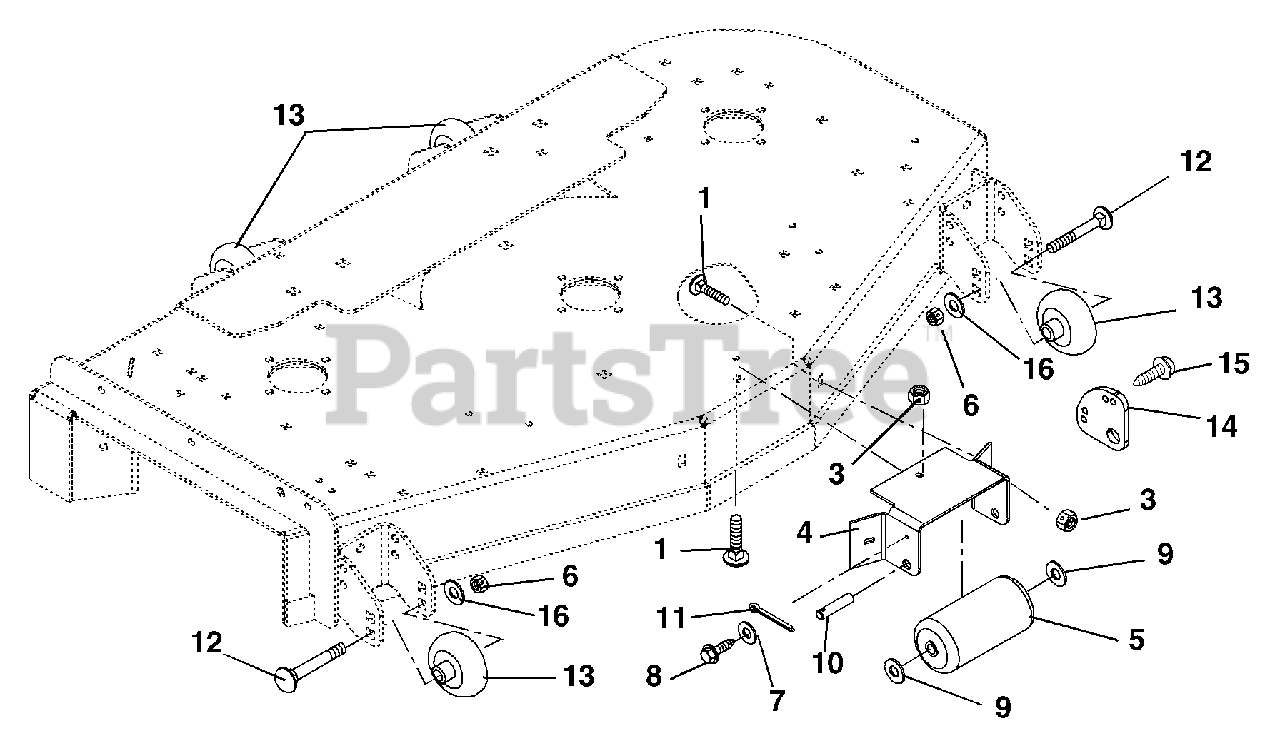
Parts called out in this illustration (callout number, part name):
1	@BLT-RDHDSQNK .38-16X1.00 G5YZ
2	@BLT-RDHDSQNK .38-16X1.25 G2YZ
3	@NUT-LK-TOP-FLG .38-16 YWZC
4	BRKT,ANTI-SCALP ROLL'R-ORANGE
4	BRACKET, ANTI-SCALP ROLLER
6	@NUT-LK-NYL .50-13 YWZC
7	@WSHR-FL-STL.281X.62X.065 YWZC
8	SCR-TAP .25-20X.75 HWH TR YWZ
9	@WSHR-FL-STL.656X1.31X.095 YWZ
11	@PIN-CTR .25X2.00 YWZC
12	BLT-RDHDSQNK .50-13X5.00 GR5YZ
13	WHEEL, 3X5
14	ANTI-SCALP WASHER - ORANGE
15	SCR-TAP.250-20X.62 HWH BLK ZC
16	@WSHR-FL-STL.531X1.06X.095YWZC
